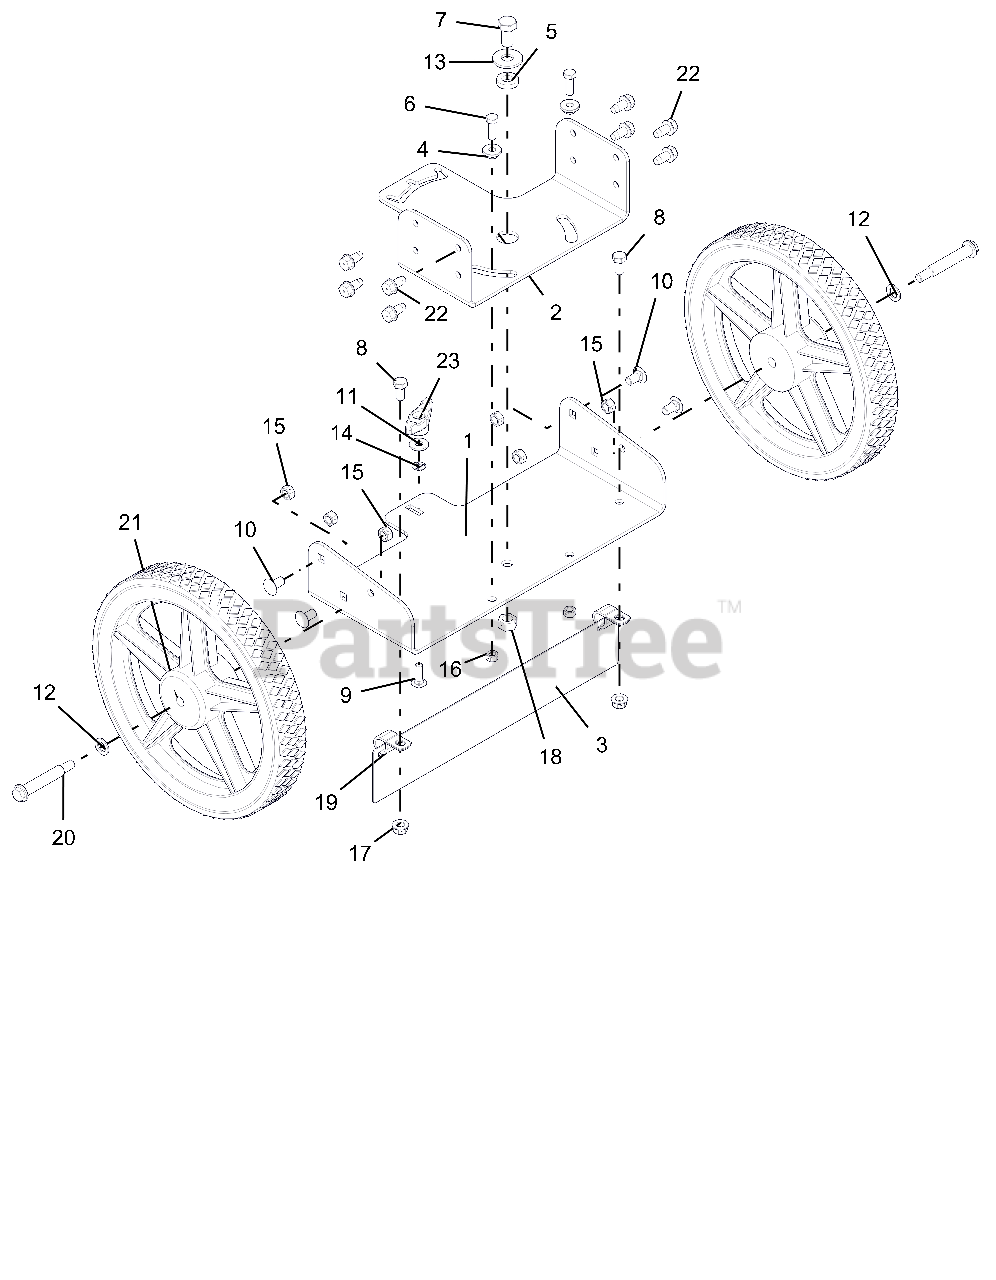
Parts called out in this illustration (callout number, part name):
1	FRAME, SWIVEL BOTTOM
2	FRAME, SWIVEL TOP
3	GUARD - REAR SWIVEL
4	BSHG-FLG .32X.500X.344X.880
5	SPACER .531 X 1.00 X .225
6	@BLT-HEX .31-18X1.00 GR5 YWZC
7	@BLT-HEX .50-13X1.00 GR5 YWZC
8	@BLT-HEX .38-16X.75 GR5 YWZC
9	@BLT-RDHDSQNK .31-18X1.00 G5YZ
10	@BLT-RDHDSQNK .38-16X.75 G5YZ
11	@WSHR-FL-STL.38X.875X.083 YWZC
12	WSHR-FL-STL .52X.827X.062 YWZC
13	@WSHR-FL-STL.563X1.38X.109YWZC
14	NUT-PUSH .312
15	@NUT-LK-CTR .38-16 YWZC
16	@NUT-LK-CTR .31-18 YWZC
17	NUT-LK-CTR-FLG .38-16 YWZC
18	@NUT-LK-CTR .50-13 YWZC
19	CLAMP, CUSHIONED STEEL .75
20	BLT-SHLDR .38-16X2.50 HWH G5
21	WHEEL-12.000 X 1.750 X .500
22	@SCR-TAP .38-16X.75 HWH TR YWZ
23	KNOB,WING .31-18 UNC NYL/TALC
